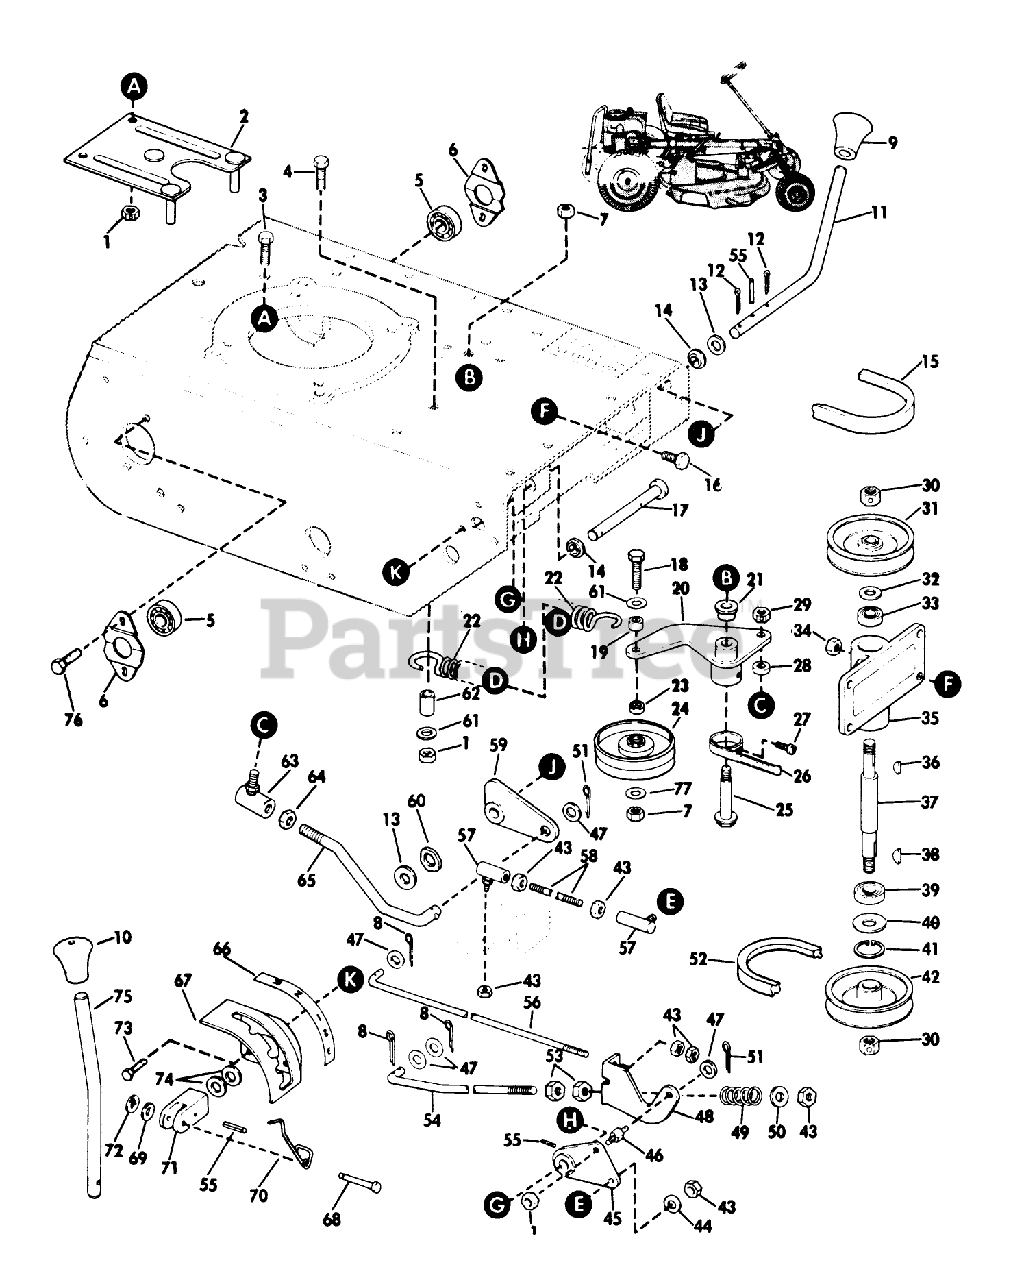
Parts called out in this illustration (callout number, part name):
7	LOCKNUT
12	Cotter Pin
20	Hub and Bell Arm Assembly
43	STOP NUT
53	STOP NUT
